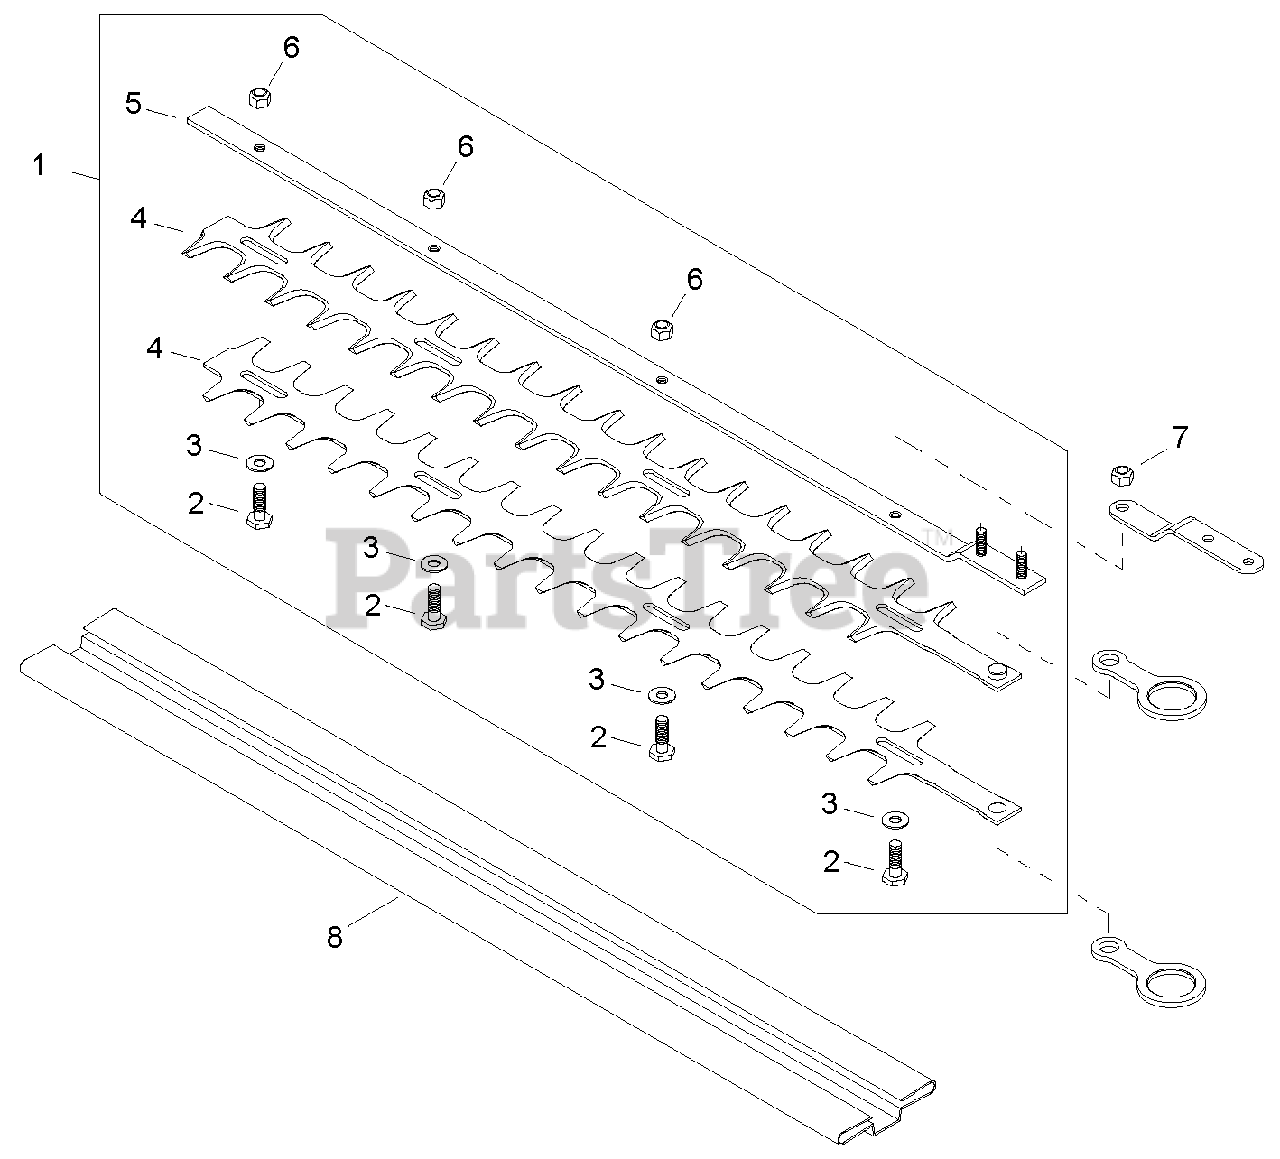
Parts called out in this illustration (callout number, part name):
2	BOLT M6×20
3	WASHER M6
4	CUTTER, CHROME 22"
5	GUIDE BAR 22"
6	NUT, LOCK M6
7	NUT, LOCK M6
8	SCABBARD
12-1	CUTTER ASSY, 22" CHROME
